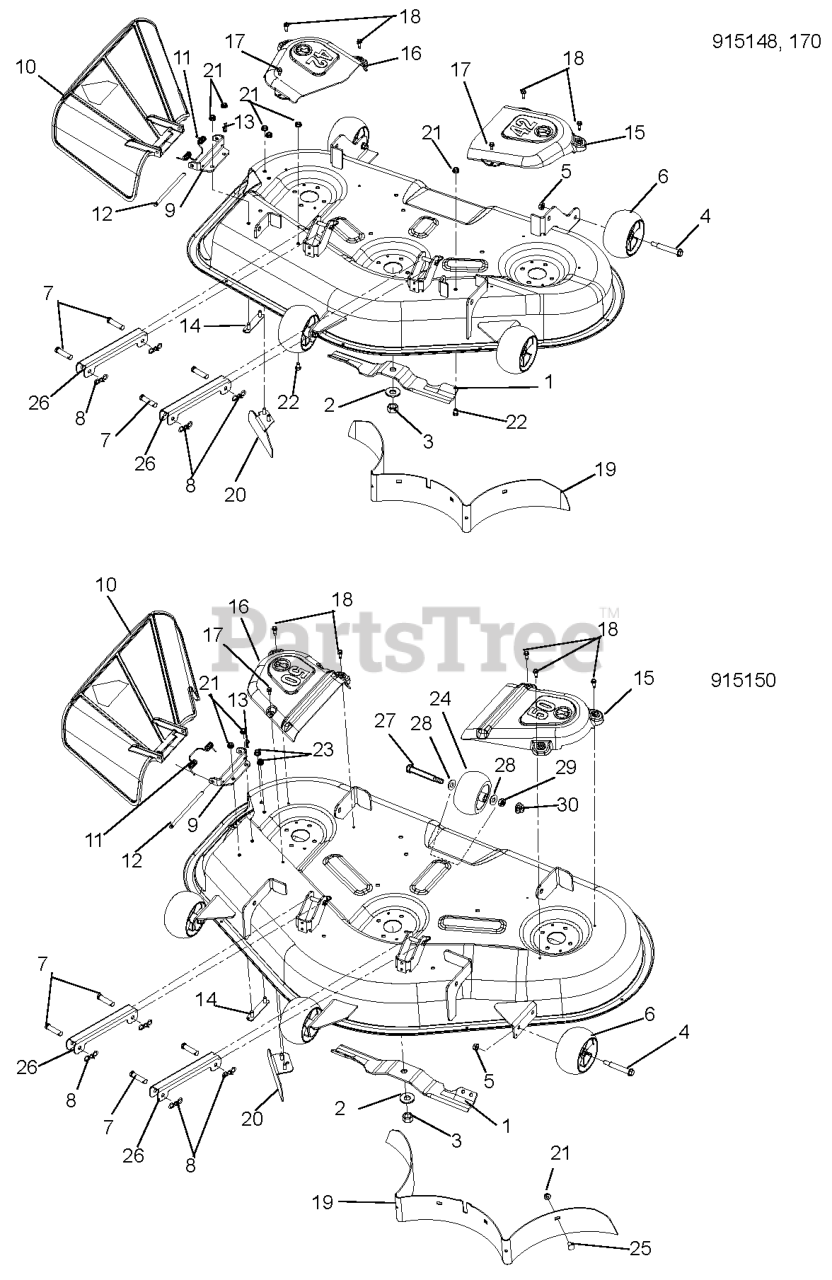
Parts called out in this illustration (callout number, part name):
1	Mower Blade, 14.83" (915148, 170)
2	Washer, Bellville .63 x 1.625 x .14
3	Nut, Hex .62-18
4	Bolt, Shoulder .38-16 x 2.50 Hex Washer Head
5	Nut, Locking, Top, Flange .38-16
6	Anti-Scalp Wheel, 5 x 3 OS (915148, 170)
7	Pin, Clevis .375 x 2.00
8	Pin, Bow Tie Locking Cotter
9	Bracket, Discharge Chute Mount 42" (915148, 170)
10	Discharge Chute
11	Spring, Torsion
12	Pin, 5/16 x 5.80"
13	Pin, Hair Internal .08 x .18 x 1.18
14	Weldment, Discharge Chute MT. Strap
15	Belt Cover, Left Hand 42" (915148, 170)
16	Belt Cover, Right Hand 42" (915148, 170)
17	Screw, Tapping .25-20 x .50 Hex Washer Head (915148, 170)
18	Screw, Tapping .25-20 x .75 Hex Washer Head
19	Baffle, 42 Rear (915148, 170)
20	Baffle, 42" Deflector (915148, 170)
21	Nut, Locking, Top, Flange .31-18 (915148, 170)
22	Bolt, Hex .31-18 x .50 (915148, 170)
23	Nut, Locking, Nylon, Flange .31-18 (915150)
24	Roller (915150)
25	Bolt, Round Head Square Neck .31-18 x .75 (915150)
26	Bracket, Stabilizer Link
27	Bolt, Hex .38-16 x 3.50
28	Washer, Flat, Steel .406 x .812 x .065
29	Nut, Locking, Center, Jam .375-16
30	Nut, Locking, Nylon, Flange .38-16
